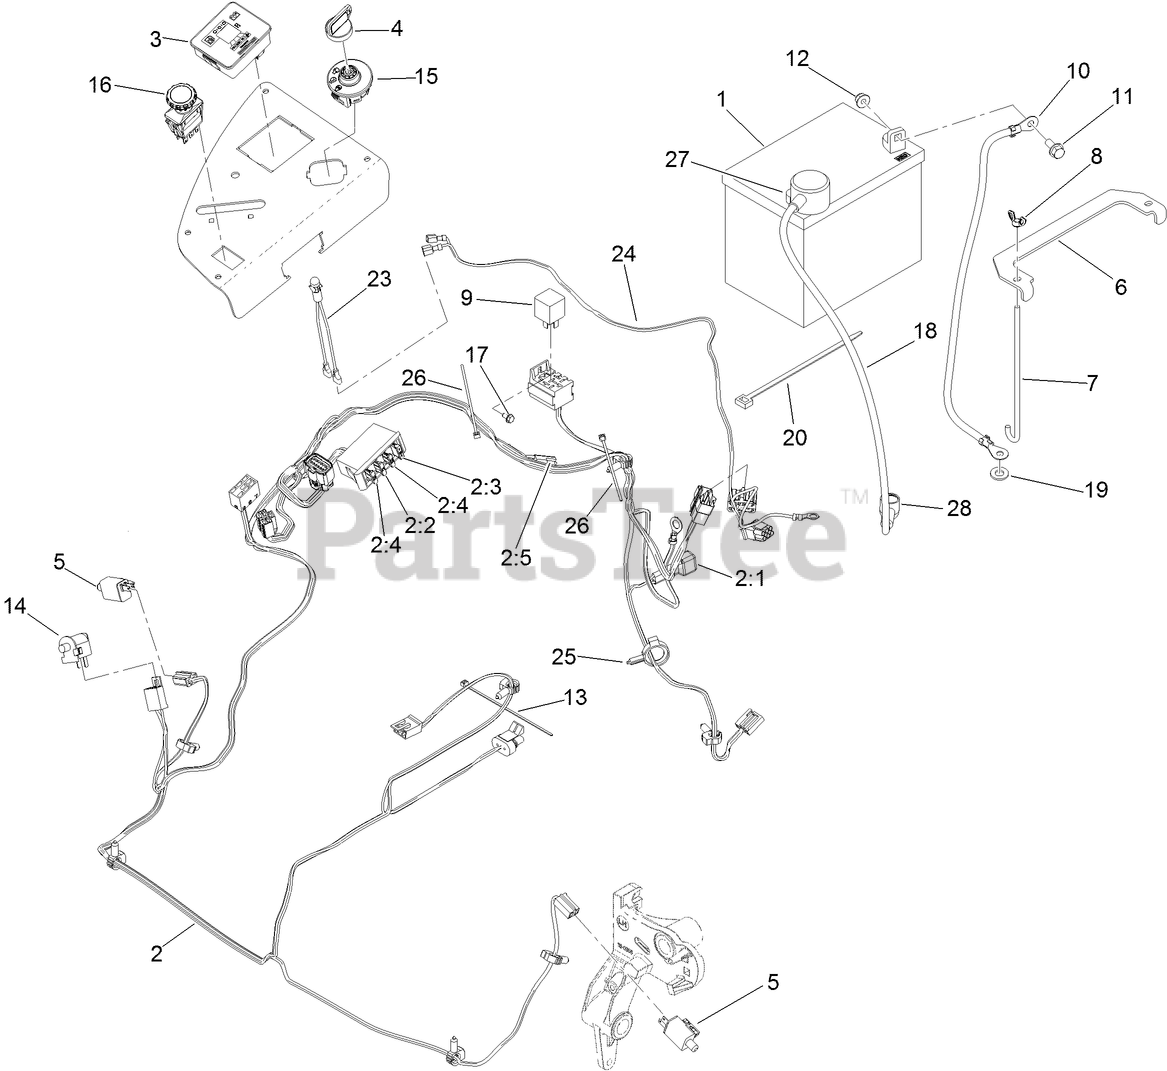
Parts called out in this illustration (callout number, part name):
1	Battery
2	HARNESS-WIRE, MAIN
2:2	FUSE-BLADE, 10 AMP
2:3	FUSE-BLADE, 15 AMP
2:4	FUSE-BLADE, 25 AMP
2:5	CAP-PLUG
3	FUEL/HOUR METER ASM
4	KEY-IGNITION
5	SWITCH
6	STRAP-TIE DOWN, BATTERY
7	BOLT-HOLDDOWN
8	WINGNUT
10	CABLE-BATTERY, NEGATIVE
11	SCREW-HHF
12	NUT-HF, NI
13	TIE-CABLE
14	SWITCH-BAIL
15	SWITCH-IGNITION
16	SWITCH-PTO, 10 AMP
17	SCREW-HWH
18	CABLE-BATTERY, POSITIVE
19	WASHER-FLAT
20	TIE-PLASTIC
23	INDICATOR-LED, RED
24	HARNESS-LIGHT, INDICATOR
25	CLAMP-HOSE
26	TIE-CABLE
27	INSULATOR-BATTERY
28	INSULATOR-SOLENOID
